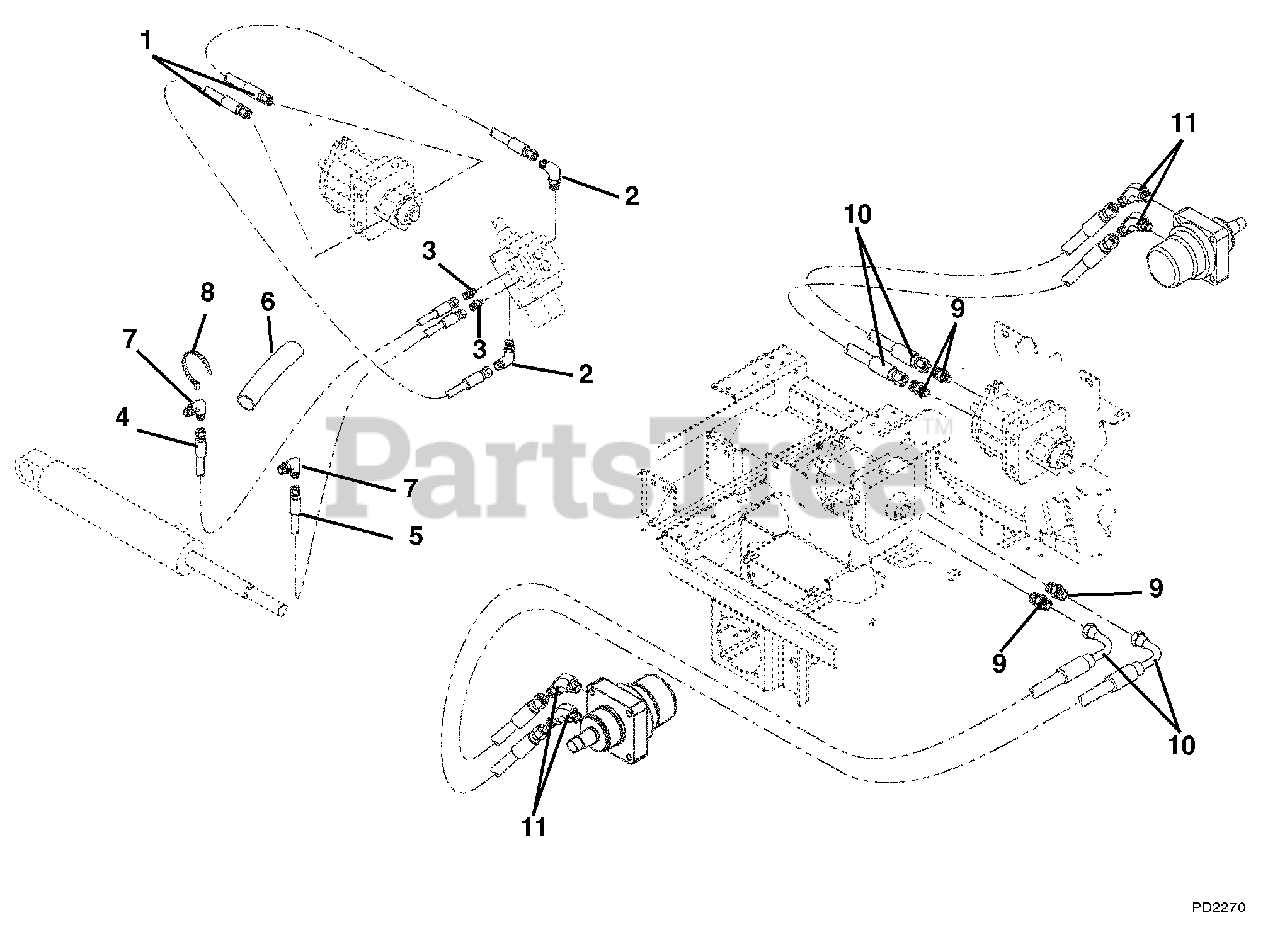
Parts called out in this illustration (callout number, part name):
1	Hose, Hydraulic
2	Hydraulic, Fitting Elbow
4	Hose, Hydraulic
5	Hose, Hydraulic
6	Sleeve Protective 24"
7	Fitting, Hydraulic
8	Cable Tie
9	Adapter, Face Seal 8 x 8 .50 O-Ring
10	Hose, Hydraulic .50
11	Adapter-Hydraulic Steel .875 to .75
